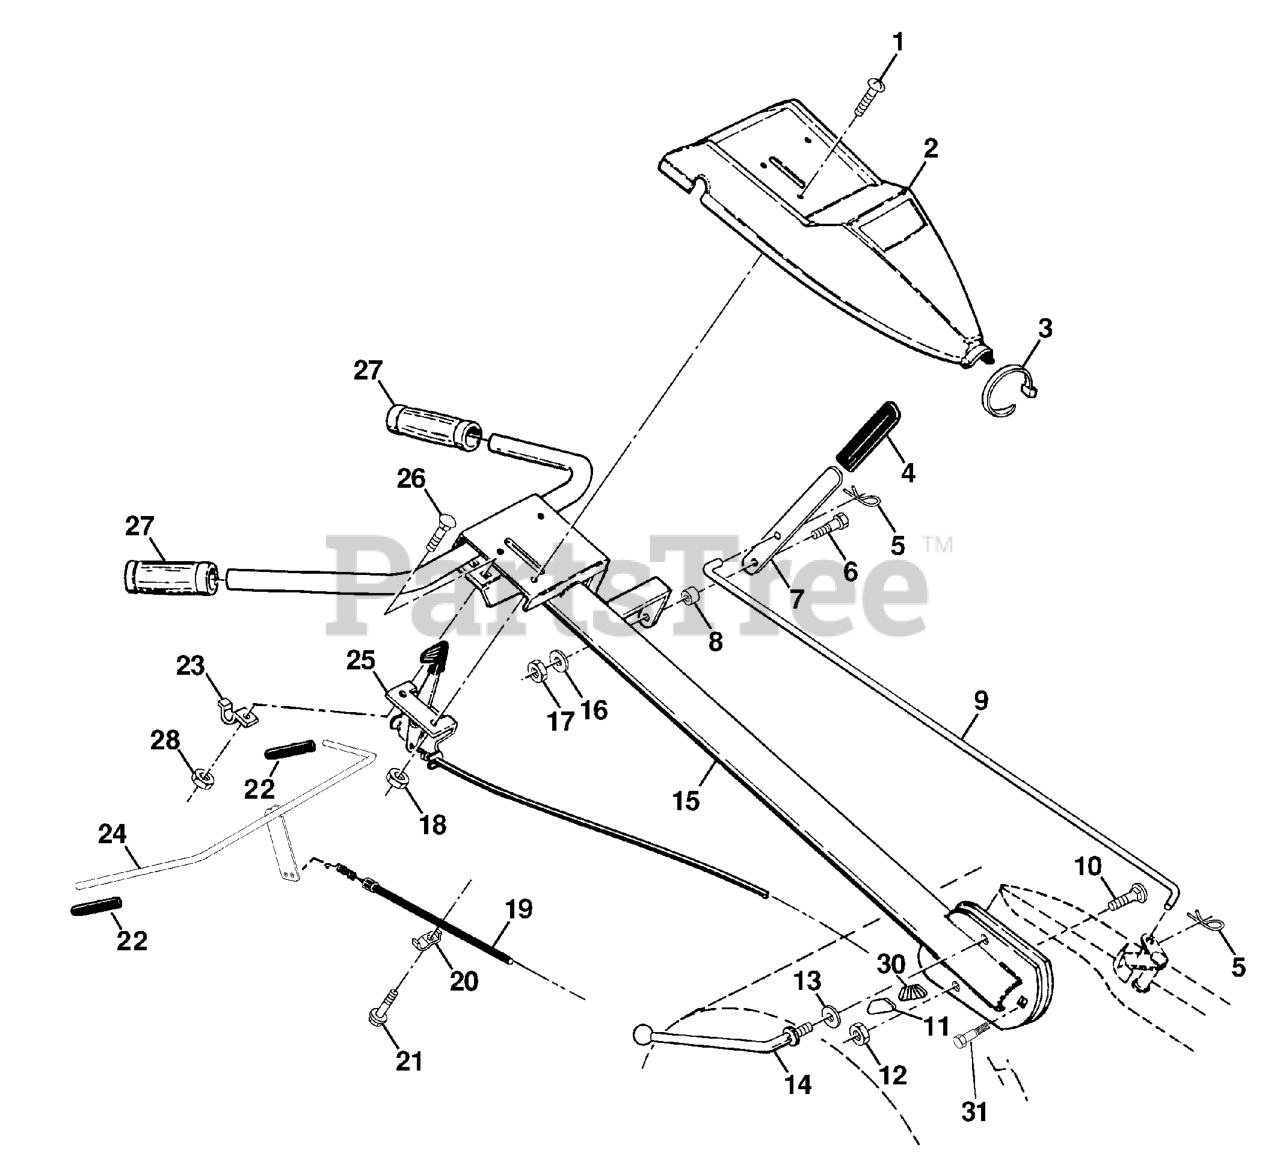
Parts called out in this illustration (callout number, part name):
1	SCREW.PNHD.10-24
3	TIE CABLE CRT
4	GRIP T
5	RETAINER M
6	SHOULDER BOLT ST
7	SHIFT HANDLE CRT
8	GROMMET.RUBBER.CRT.TILLER
9	ROD.SHIFT.YARD PRO.UNIVERSAL.
10	BOLT D
11	LOCK.HANDLE.CRT
12	LOCKNUT
13	WASHER CRT
14	LEVER.LOCK.CRT
15	HANDLE
16	LOCKWASHER
17	NUT
18	NUT **
19	CABLE.CLUTCH
20	CONDUIT.CLIP.PLATED
21	TAPPING SCREW
22	GRIP BAR CRT(1)
23	CLAMP.BAR.CRT.BLACK
24	CONTROL BAR ASSY
25	THROTTLE CONTROL
26	BOLT
27	KIT.GRIP.HANDLE.5.00.BLK.VINYL
28	NUT
30	LOCK HANDLE
31	BOLT.PIVOT
